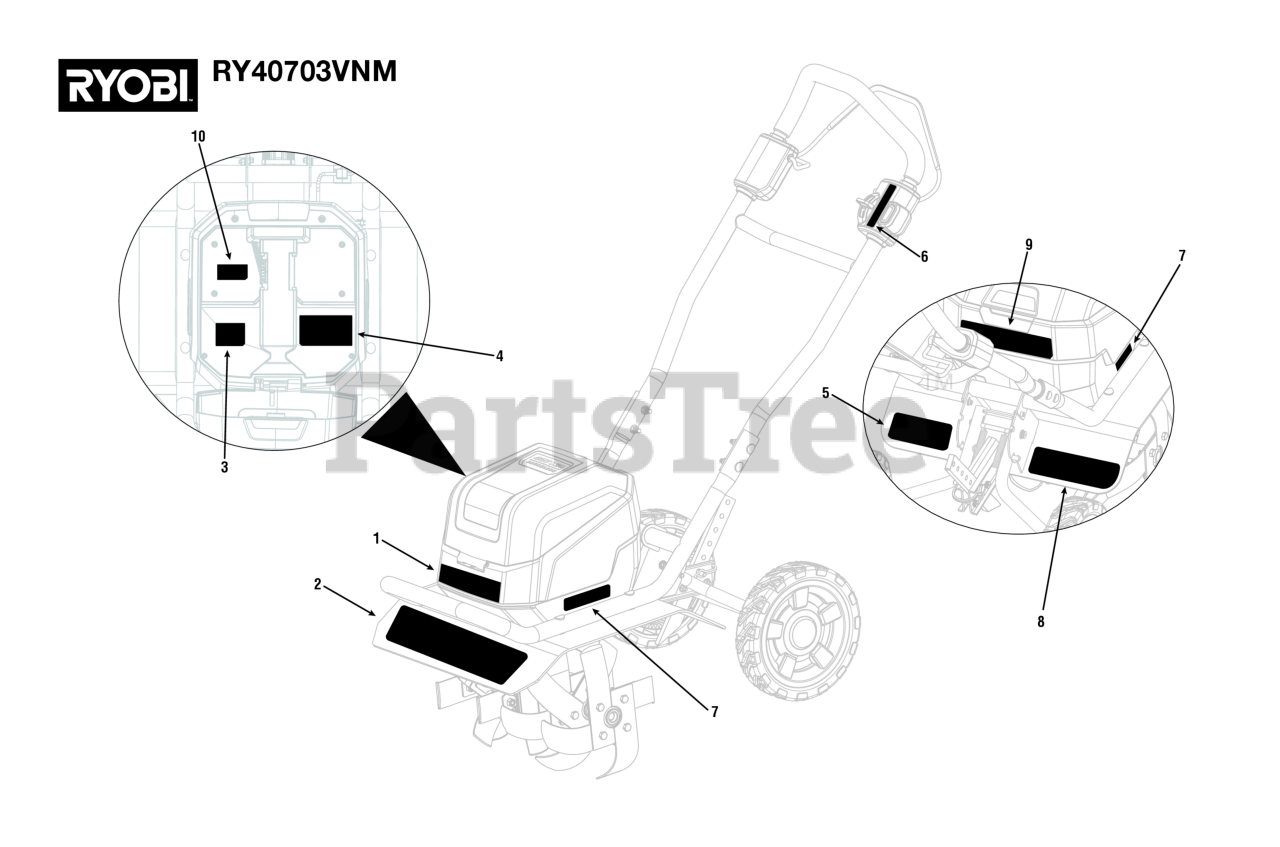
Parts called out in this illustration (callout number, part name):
1	16in Tilling Width Label
2	40V HP Brushless Label
3	QR Code Label
4	Data Label
5	Wheel Adjustment Label
6	Blade Start Label
7	Whisper Logo
8	Drag Stake / Wheels / Cut Finger Label
9	Icon/Warning Label
10	Battery Storage Label
